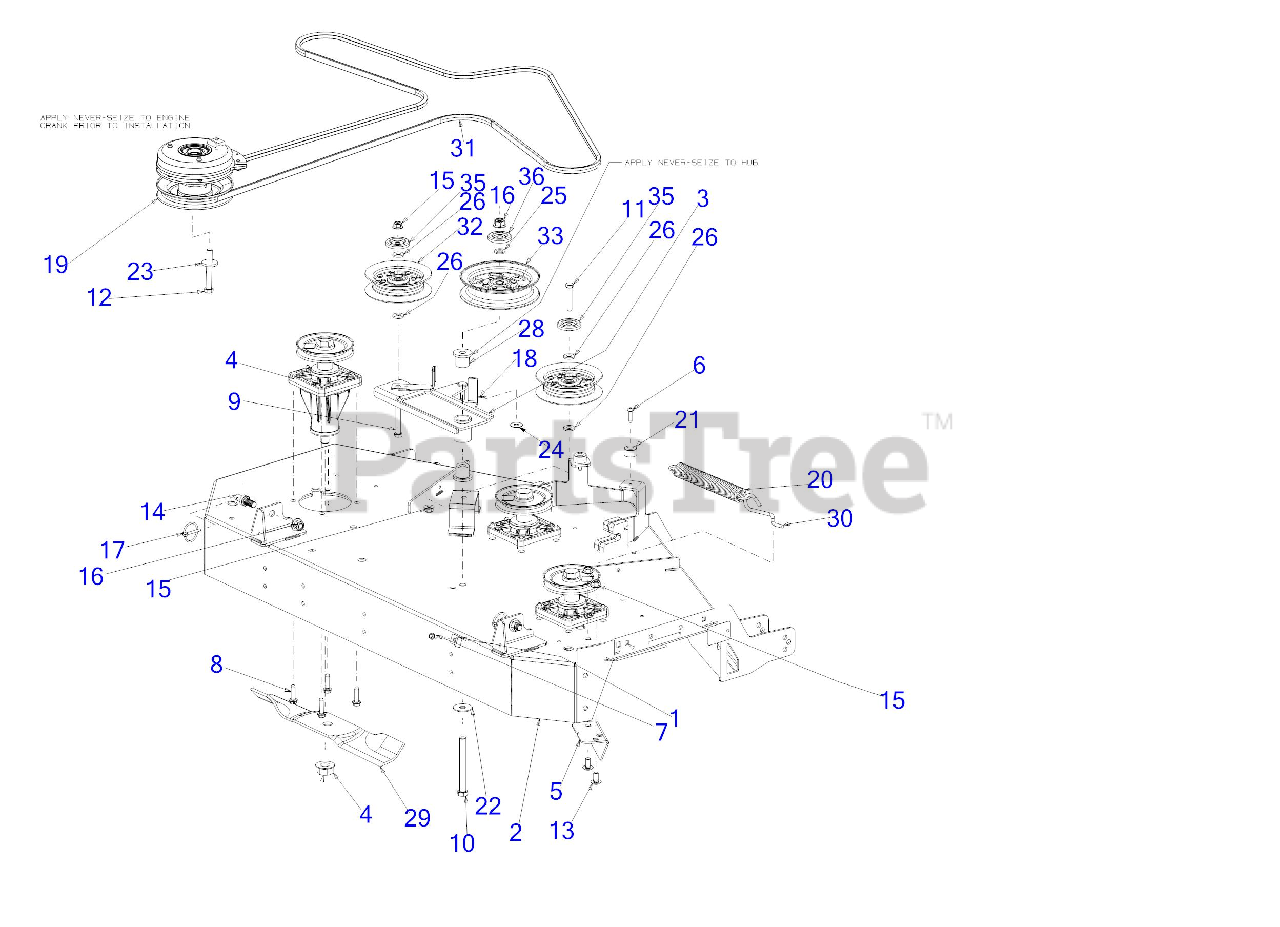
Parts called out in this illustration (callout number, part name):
1	HOOK RETAINER BRACKET
2	48" FAB DECK SHELL
3	IDLER ARM ASSEMBLY
4	SPINDLE ASSEMBLY
6	SCREW 1/4-20 x 1.0
7	SCREW 1/4-20 X.500
8	SCREW 5/16-18 x 1.25
9	HEX SCREW-3/8-16X2.5 GR5
10	SCREW 1/2-13 x 4.5 GR 5
11	SCREW 3/8-16 x 2.0 GR5
12	SCREW 7/16-20 x 3.25 GR5
13	CARRIAGE BOLT 3/8-16 x .75
18	COTTER PIN 3/32
19	ELECTRIC PTO CLUTCH
20	EXTENSION SPRING
22	WASHER .51 x 1.5 x .07
23	FLAT WASHER .445 x 1.248 x .170
24	FLAT WASHER
25	FLAT WASHER
26	FLAT WASHER
28	SHOULDER SPACER
29	17" BLADE (HI LIFT)
30	DECK SPRING HOOK
31	DECK BELT A SEC x 137"
32	IDLER PULLEY 4.0
33	IDLER PULLEY 5.0"
35	IDLER PULLEY CAP
36	PULLY CAP 1/2"
